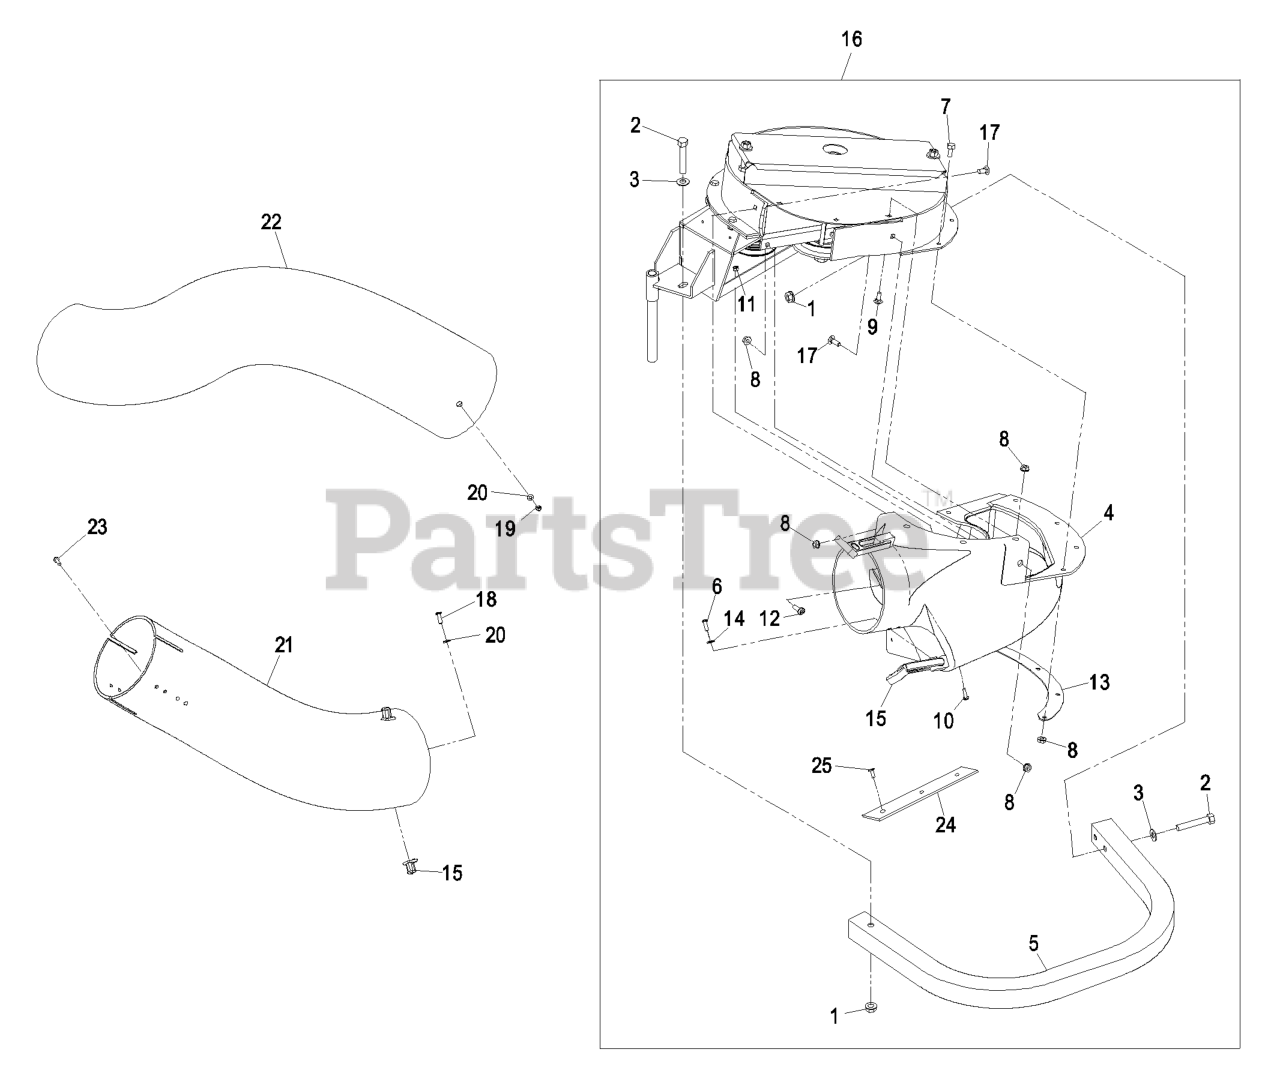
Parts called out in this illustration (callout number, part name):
1	NUT-HHF, WHIZ
2	SCREW-HH
3	WASHER-FLAT
4	ASM,BLOWER CHUTE SMALL
6	SCREW-PPH
7	SCREW-HH
9	SCREW-CARR
10	SCREW-HEAD, TRUSS
13	PLATE-BACKING, BLOWER
14	WASHER-FLAT
15	LATCH DRAW
16	ASM,BLOWER 44/48 - SERVIC
17	BOLT-CARR
18	SCREW-PPH
19	NUT-LOCK, NI
20	WASHER-FLAT
21	KIT,LOWER TUBE
22	TUBE,UPPER 46/50
23	SCREW-HWH
24	PLATE-REINFORCEMENT
25	RIVET-BLIND
